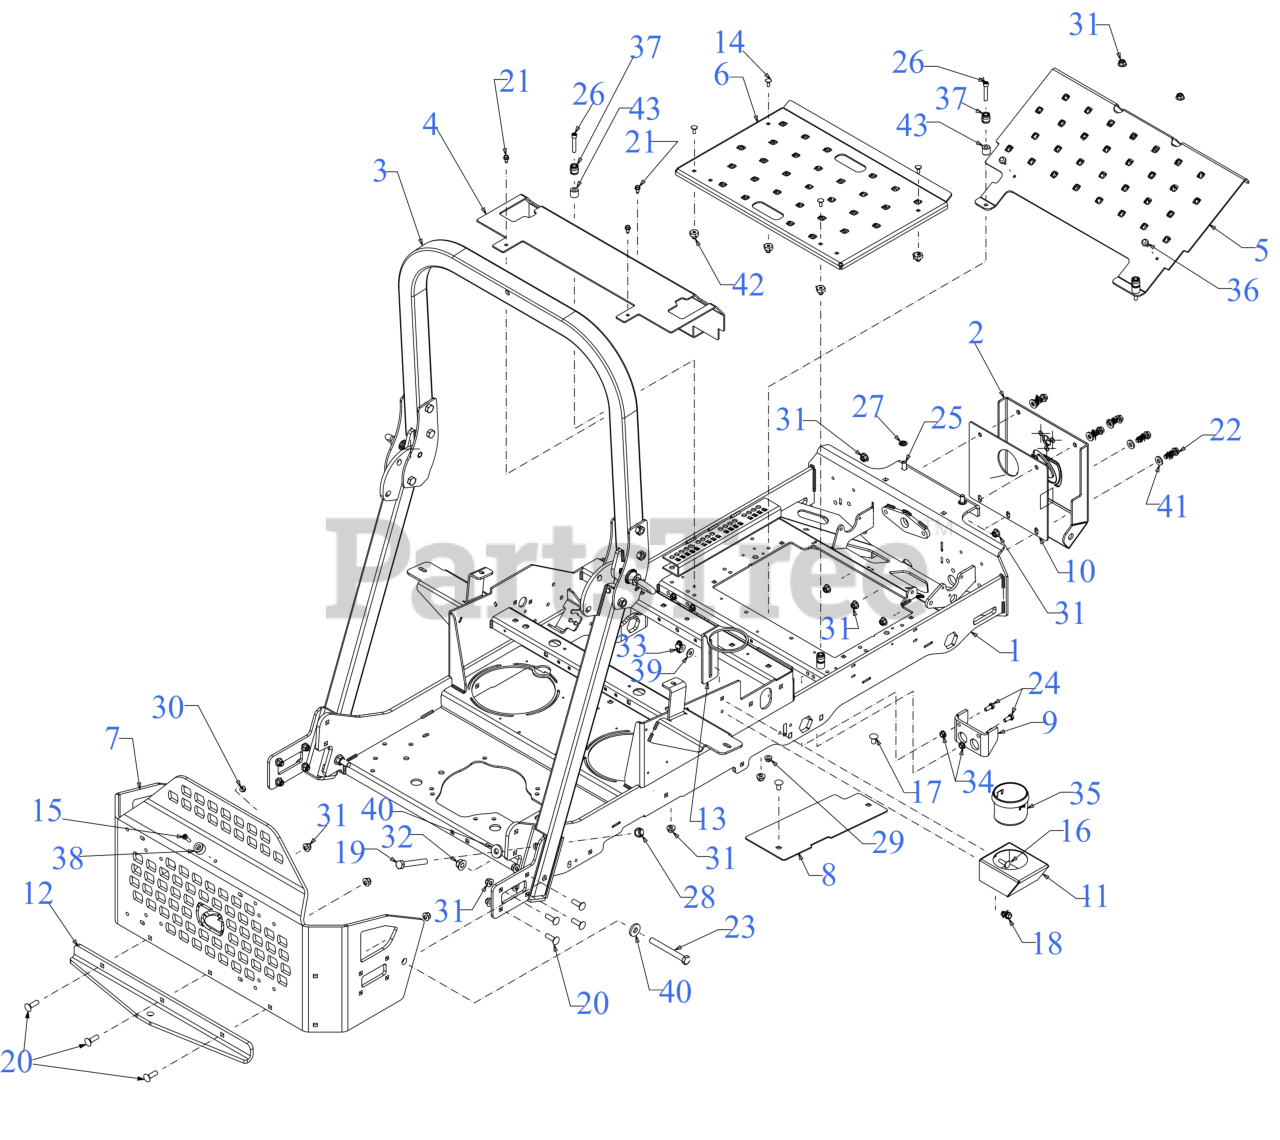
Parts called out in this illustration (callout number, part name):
1	FRAME ASSEMBLY
3	PRO Z ROPS KIT
10	FRONT MOUNTING PLATE SPACER
14	CARRIAGE BOLT 1/4-20 x .62
15	MACHINE SCREW 1/4-20:1
16	CARRIAGE BOLT 5/16-18 x 1.00
17	CARRIAGE BOLT 3/8-16 x .750 GR5
18	SCREW 5/16-18 x .750
19	SCREW 1/2-20 x 3.50 GR5
20	CARRIAGE BOLT 3/8-16 X1.25 GR5
21	SCREW 1/4-20 X.500
22	SCREW 3/8-16 x 1.25 GR5
23	SCREW 1/2-13 x 4.5 GR 5
24	SCREW 5/16-18 x .75 GR5
25	CARRIAGE BOLT 3/8-16 x 1.00 GR5
26	SCREW 5/16-18X1.75 GR5
28	HEX NUT CENTER
29	FLANGE LOCK NUT 5/16-18
30	FLANGE LOCK NUT
33	WING NUT 5/16-18
34	FLANGE NUT
36	BUMPER, .62 DIA x .3
37	RADIAL BUMPER
39	FLAT WASHER
40	FLAT WASHER .531 x 1.25 x .181
41	FLAT WASHER
42	SHOULDER SPACER
